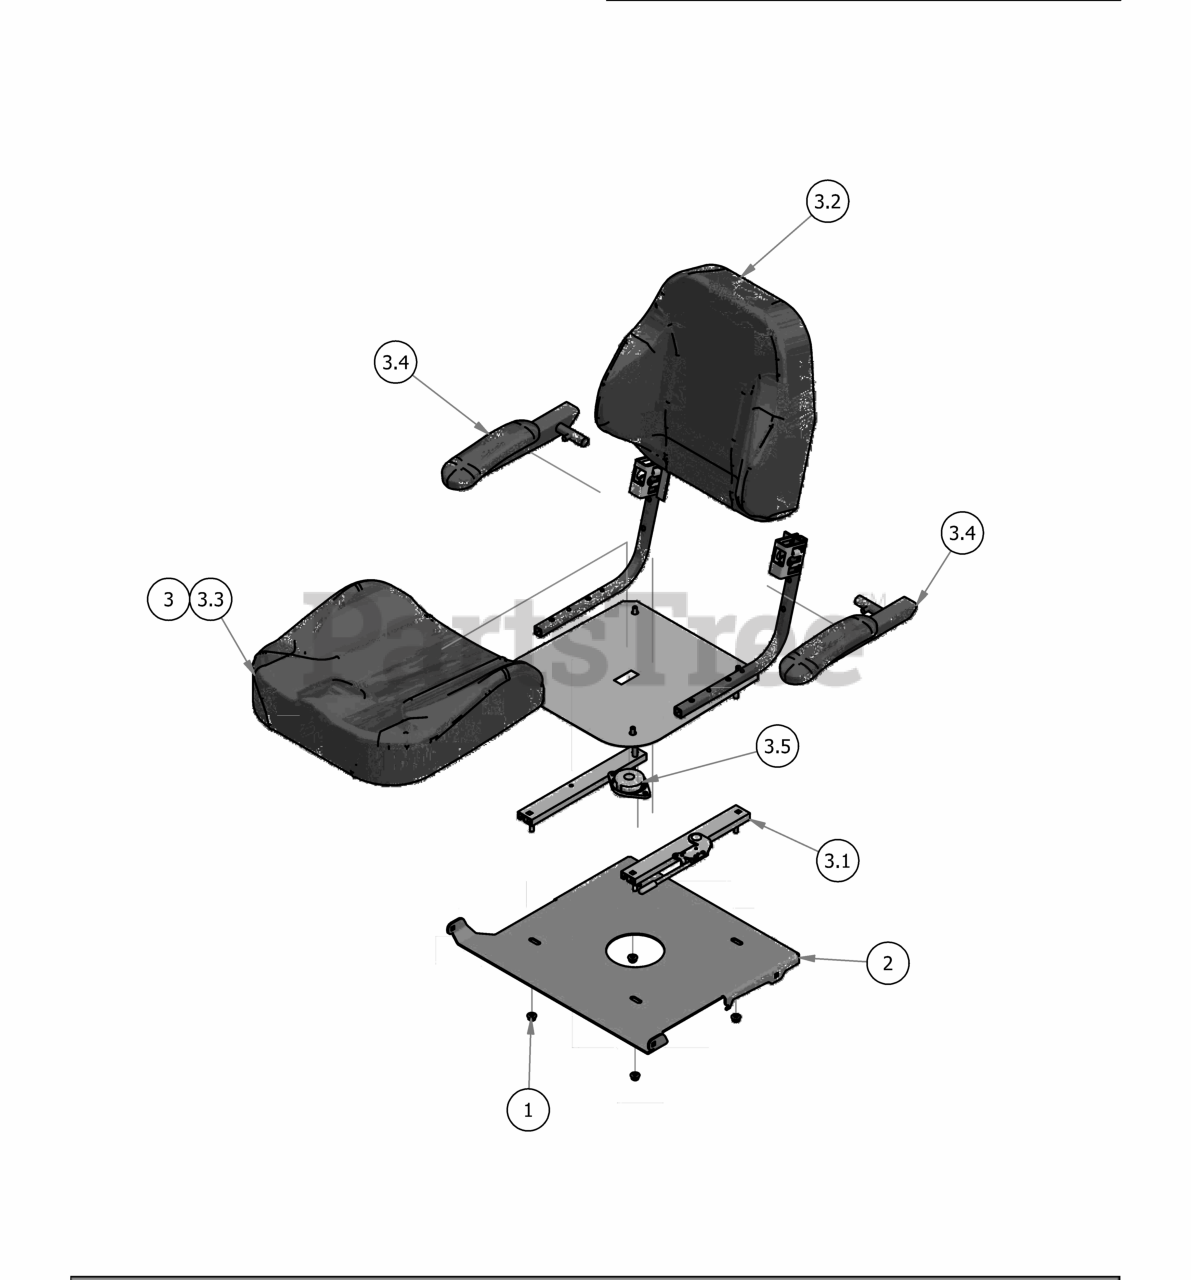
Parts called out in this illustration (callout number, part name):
1	5/16" Nylon Flange Nut
2	Seat Plate 2016
3	2018 ZT Seat
3.1	Seat Rail Pair
3.2	Seat Back Cushion
3.3	Seat Bottom Cushion
3.5	Seat Safety Switch
